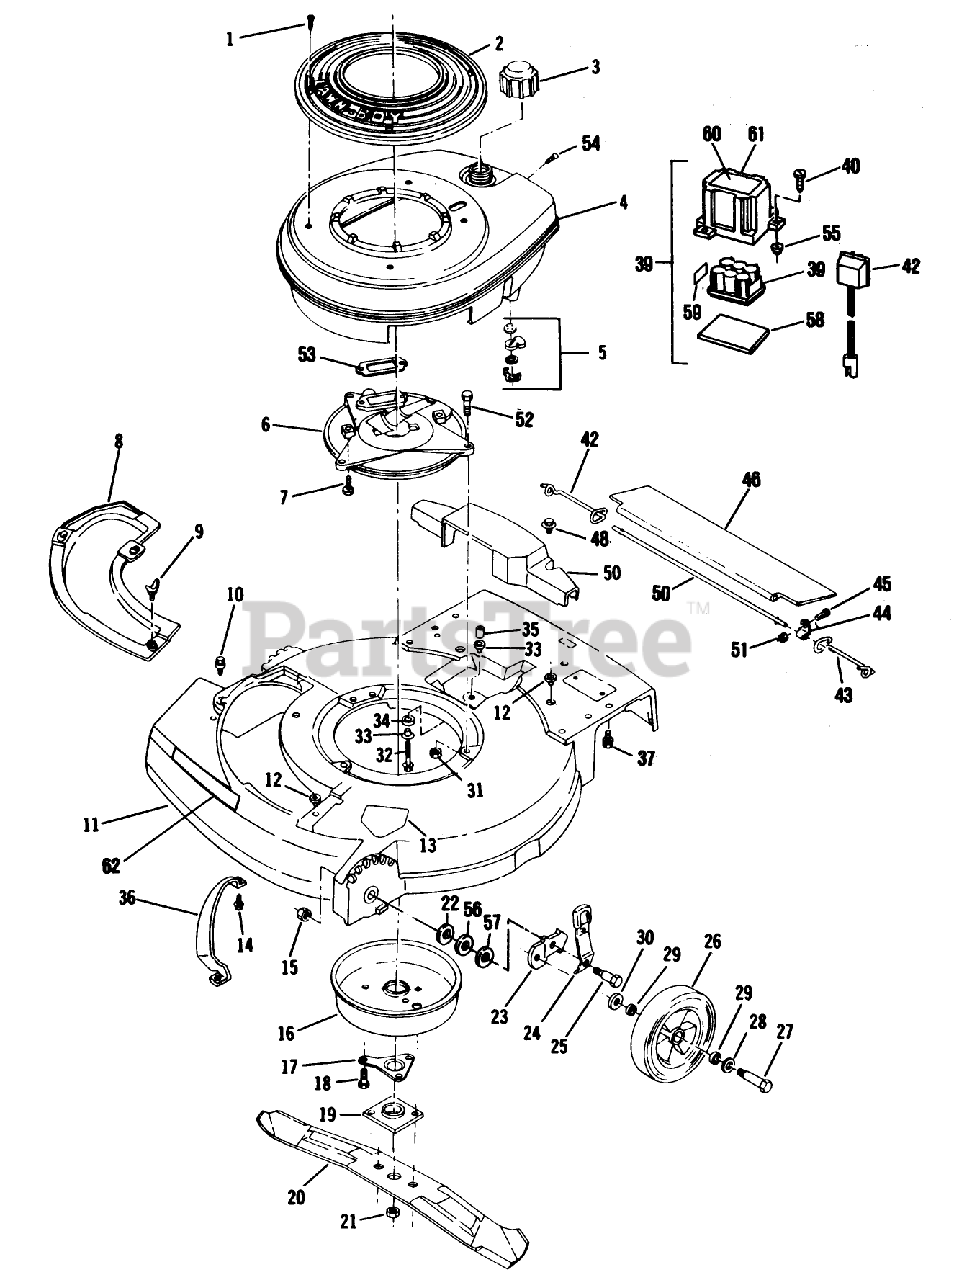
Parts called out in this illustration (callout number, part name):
1	SCREW - SELF TAPPING
3	FUEL CAP & INSERT
5	SHUT OFF VALVE KIT
7	SCREW V
9	WING SCREW LAWRE
15	LOCKNUT
16	MUFFLER COVER F
17	SUPPORT F
18	SCREW
19	PLATE AND COLLAR ASM
21	NUT-BLADE
22	WASHER
24	SPRING ARM ASM
25	BOLT
26	WHEEL & TIRE KIT
27	BOLT WHEEL
28	SPACER
29	WASHER
30	WASHER WROUGHT
31	NUT-LOCK F
33	SPACER ECK PRES
34	GROMMET
35	SPACER
36	BAR-TOE
37	SCREW
40	SCREW - SELF TAPPING
43	SPRIG T/SHLD ASOC
44	CLAMP ROD KMC
46	SHIELD
47	SPRING;TRAILING SHIELD RH
48	SCREW SEMS TRM HEX HD
50	ROD 21" ADVANCE
51	LOCKNUT E
52	SCREW-HH
54	SCREW S
55	NUT-CLIP
56	WASHER
57	WASHER
58	PAD-BATTERY
59	Decal-Batt.
